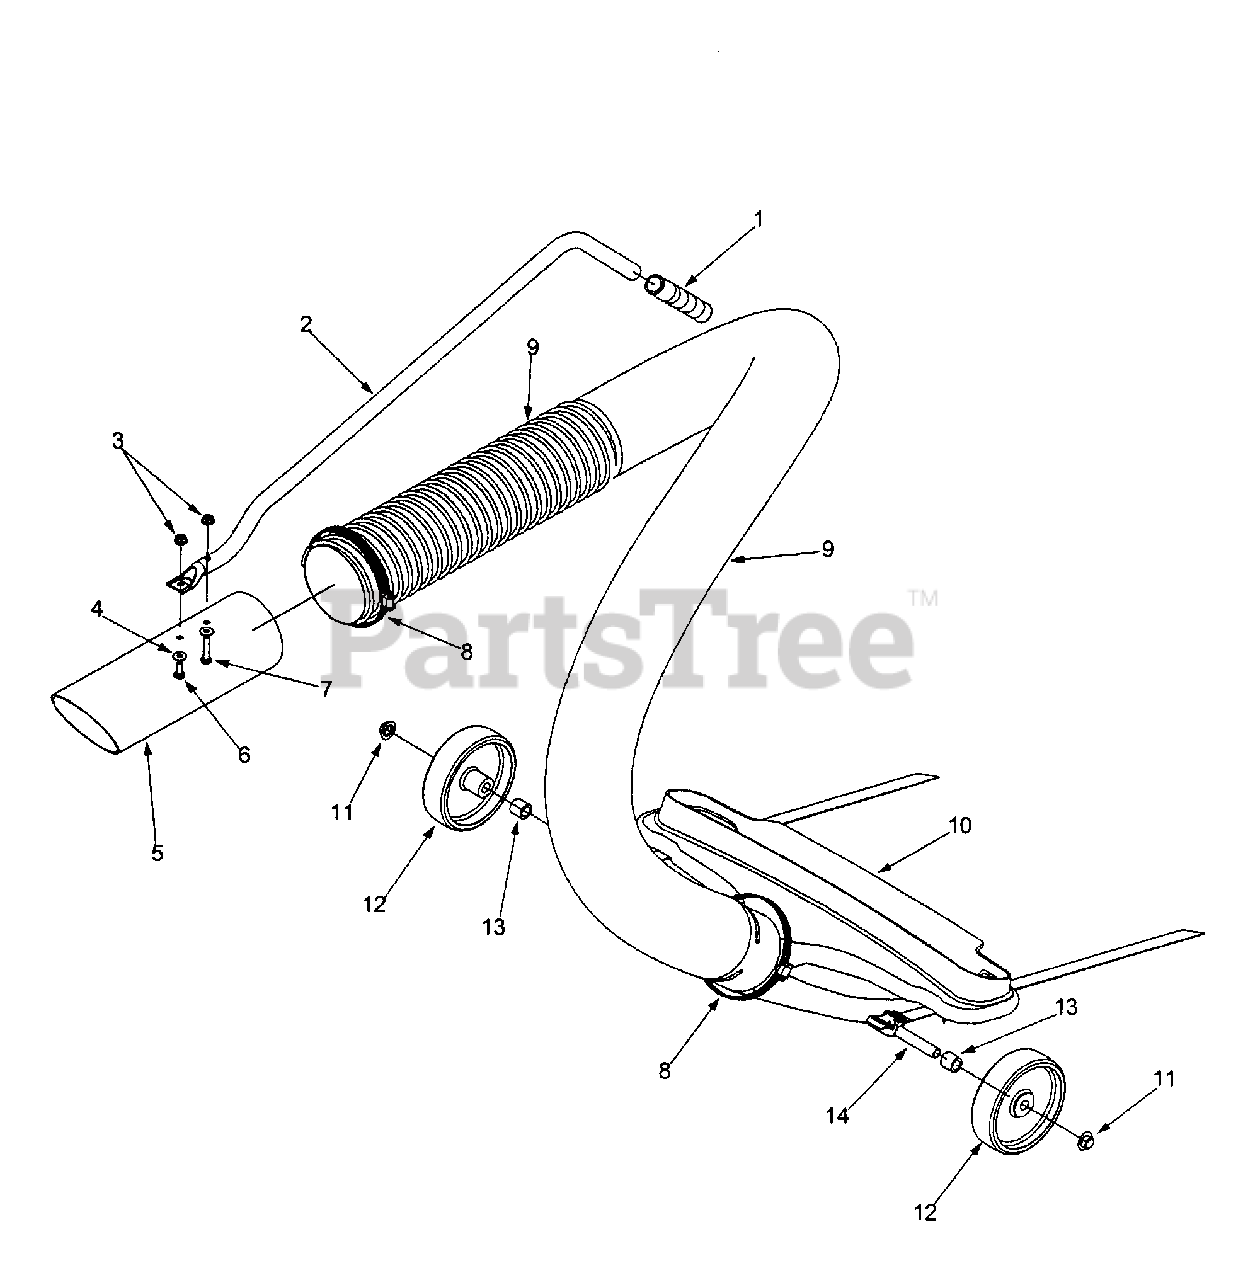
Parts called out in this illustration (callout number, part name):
1	Handle Grip
3	Hex Lock Nut 1/4-20
4	Flat Washer .271 ID x .630 OD
5	Nozzle 3.875 x 12.0
6	Hex Cap Screw 1/4-20 x .620
7	Hex Cap Screw 1/4-20 x 1.25
8	Adjustable Clamp
10	Hose Attachment Nozzle Ass'y
12	Wheel 5.0 x 1.38
14	Axle .50 OD x .354 ID x 16.7
